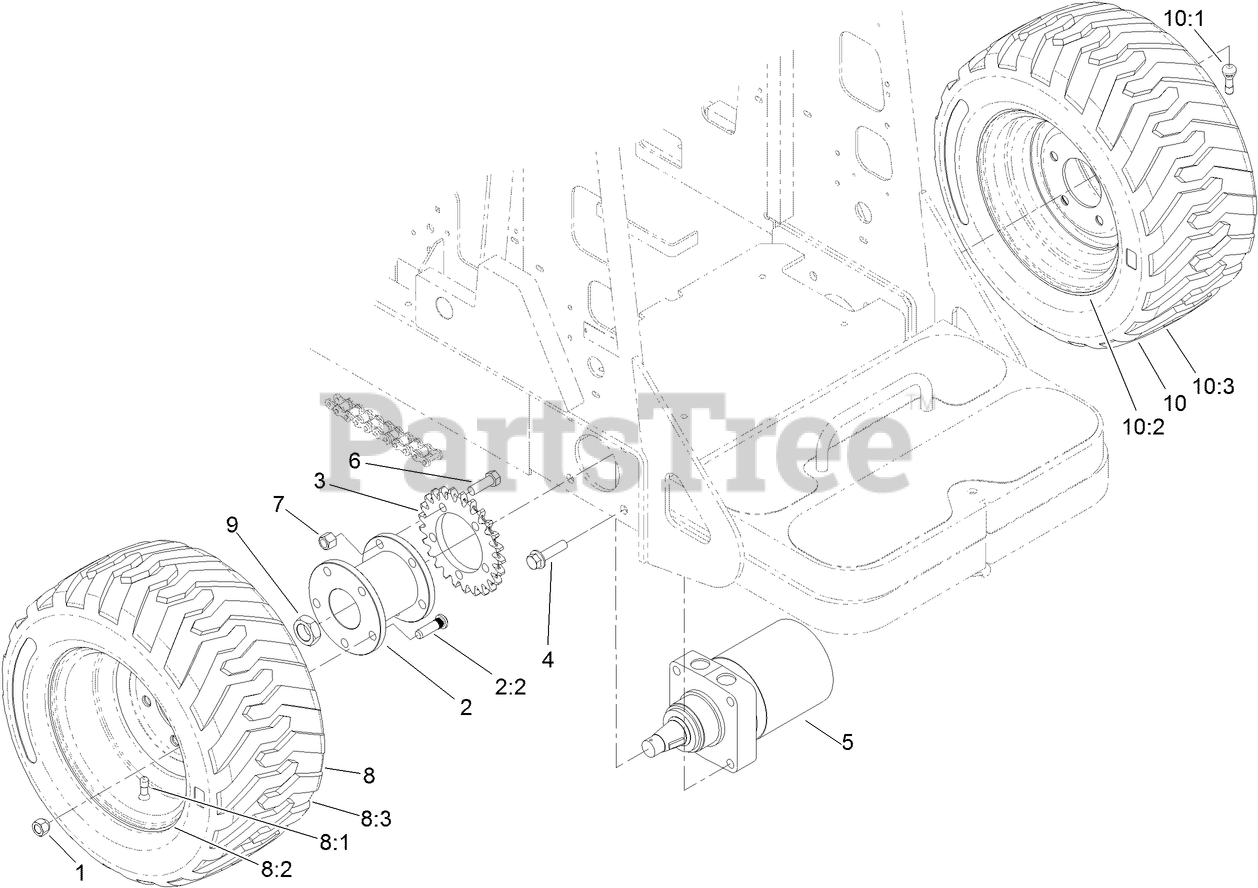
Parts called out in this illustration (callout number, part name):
1	NUT-LUG
2	REAR HUB ASM
2:2	STUD-TYPE, DRIVE
3	SPROCKET-25T
4	SCREW-HHF
5	HYD MOTOR ASM
6	SCREW-HH
7	NUT-LOCK, NI
8	LH WHEEL AND TIRE ASM
8:1	STEM-VALVE
8:2	WHEEL
9	NUT-LOCK
10	RH WHEEL AND TIRE ASM
10:1	STEM-VALVE
10:2	WHEEL
